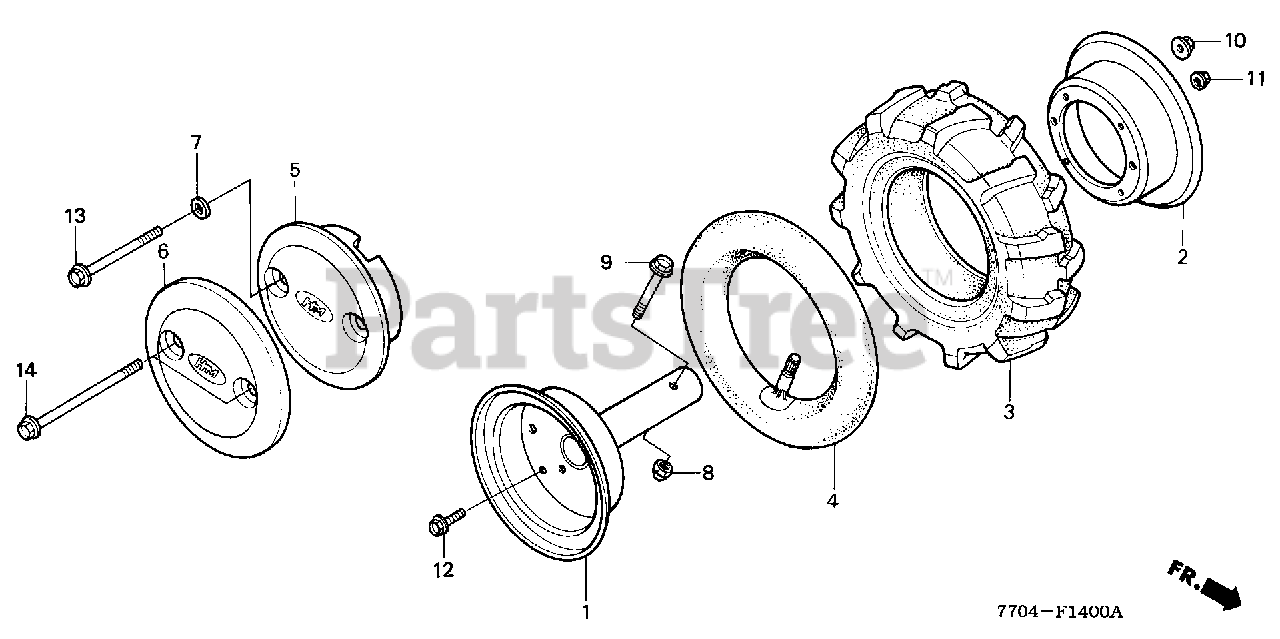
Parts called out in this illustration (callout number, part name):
1	RIM, WHEEL *NH35M* (A) (CLOUD SILVER METALLIC)
3	TIRE (3.50-7)
4	TUBE (3.50/4.00-7)
5	WEIGHT A, WHEEL
6	WEIGHT B, WHEEL
8	NUT, SELF-LOCK (8MM) (CLINCH)
9	BOLT, FLANGE (8X55)
10	NUT, FLANGE (10MM)
11	NUT-WASHER (8MM)
12	BOLT, FLANGE (8X16)
13	BOLT, FLANGE (10X65)
14	BOLT, FLANGE (10X100)
